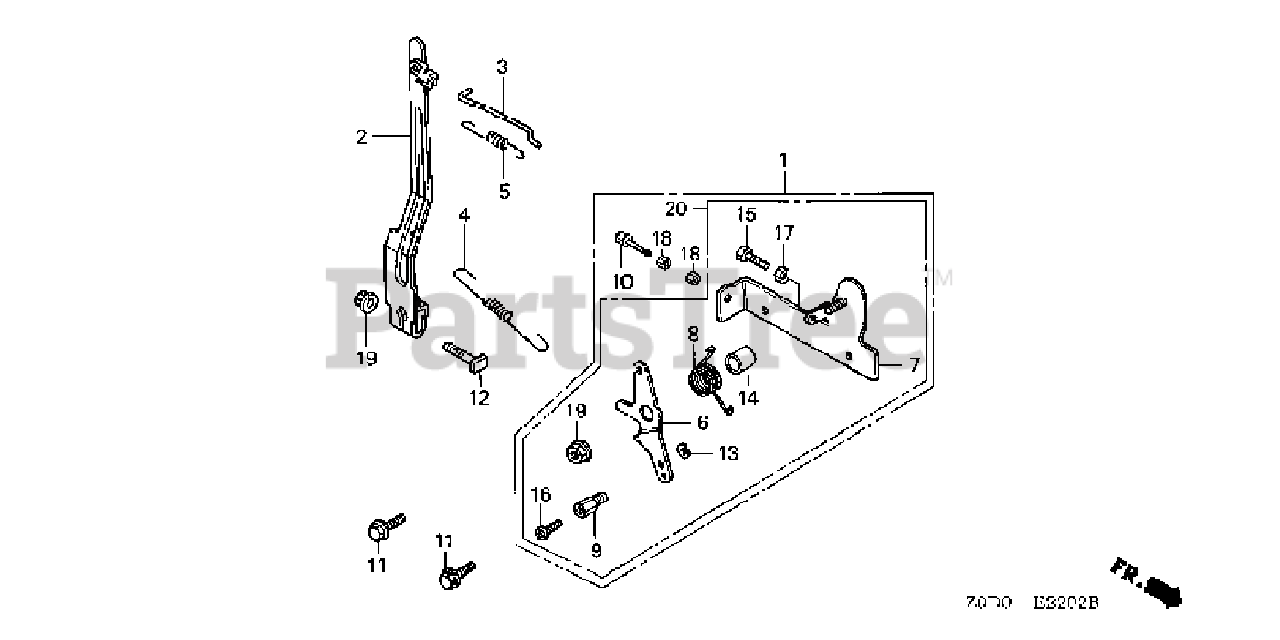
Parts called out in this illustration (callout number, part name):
2	ARM, GOVERNOR
3	ROD, GOVERNOR
4	SPRING, GOVERNOR
5	SPRING, THROTTLE RETURN
6	LEVER, CONTROL (REMOTE)
7	BASE, CONTROL (REMOTE)
8	SPRING, CONTROL LEVER RETURN
9	HOLDER, WIRE
11	BOLT, FLANGE (6X14)
12	BOLT, GOVERNOR ARM
13	CIRCLIP (5MM)
14	COLLAR, CONTROL LEVER
15	BOLT, HEX. (5X20)
16	SCREW, PAN (4X6)
17	NUT, HEX. (5MM)
19	NUT, FLANGE (6MM)
20	CONTROL ASSY. (BOMAG)
